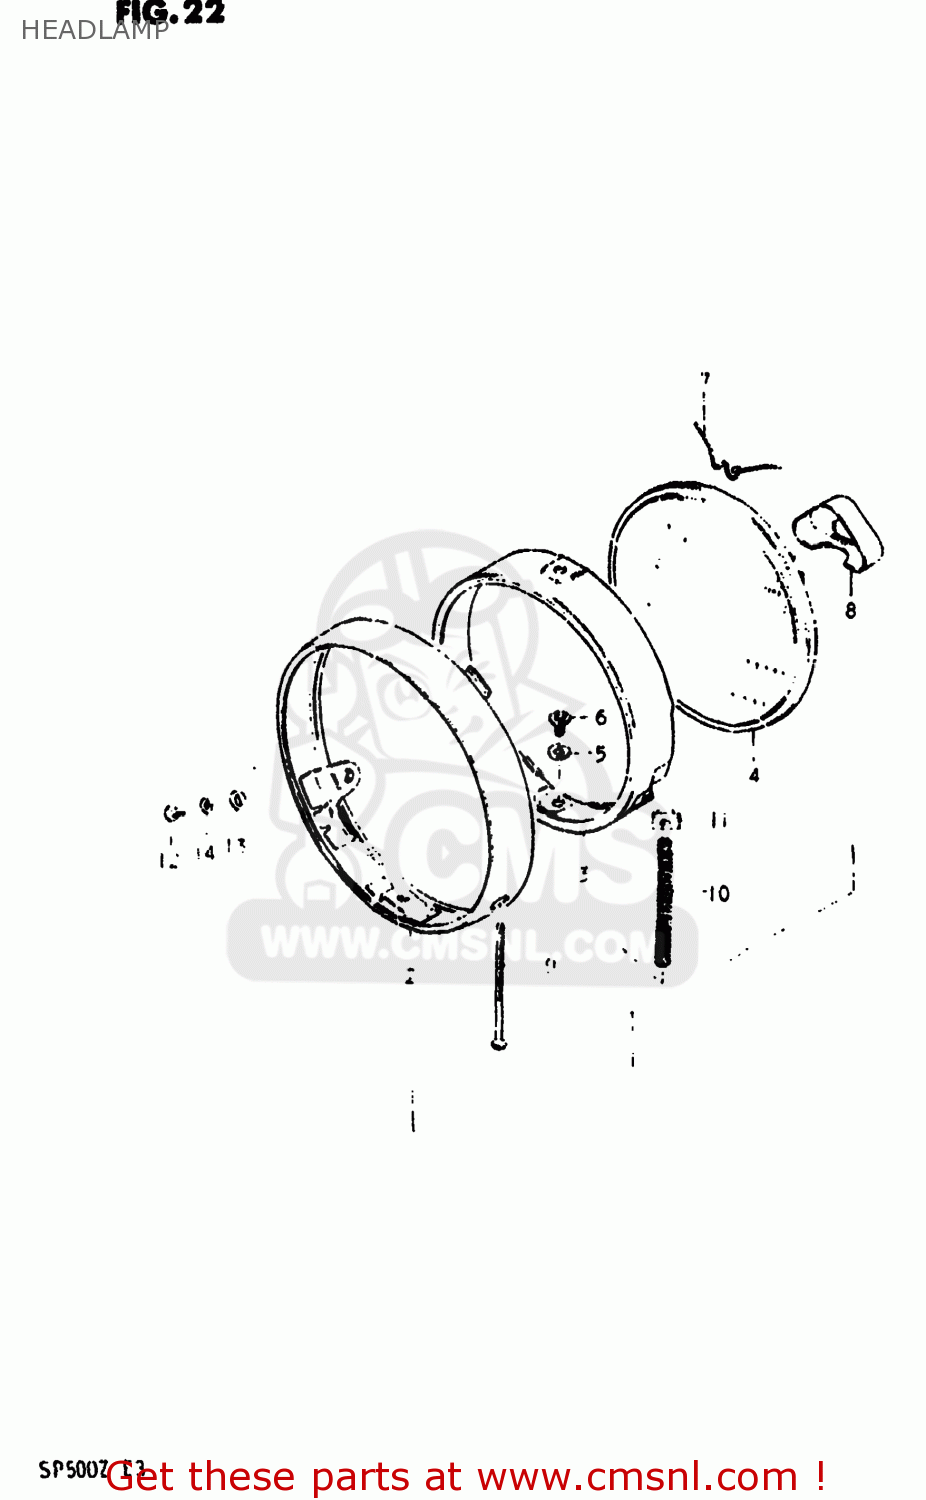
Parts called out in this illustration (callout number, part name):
1	HEADLAMP ASSEMBLY
2	RIM,HEADLAMP
3	RETAINER
4	LAMP UNIT
5	LOCK WASHER
6	SCREW
7	SPRING,HEAD LAMP UNIT
8	COVER
9	SCREW
10	SPRING,HEADLAMP ADJUST
11	NUT
12	SCREW
13	WASHER
14	LOCK WASHER
